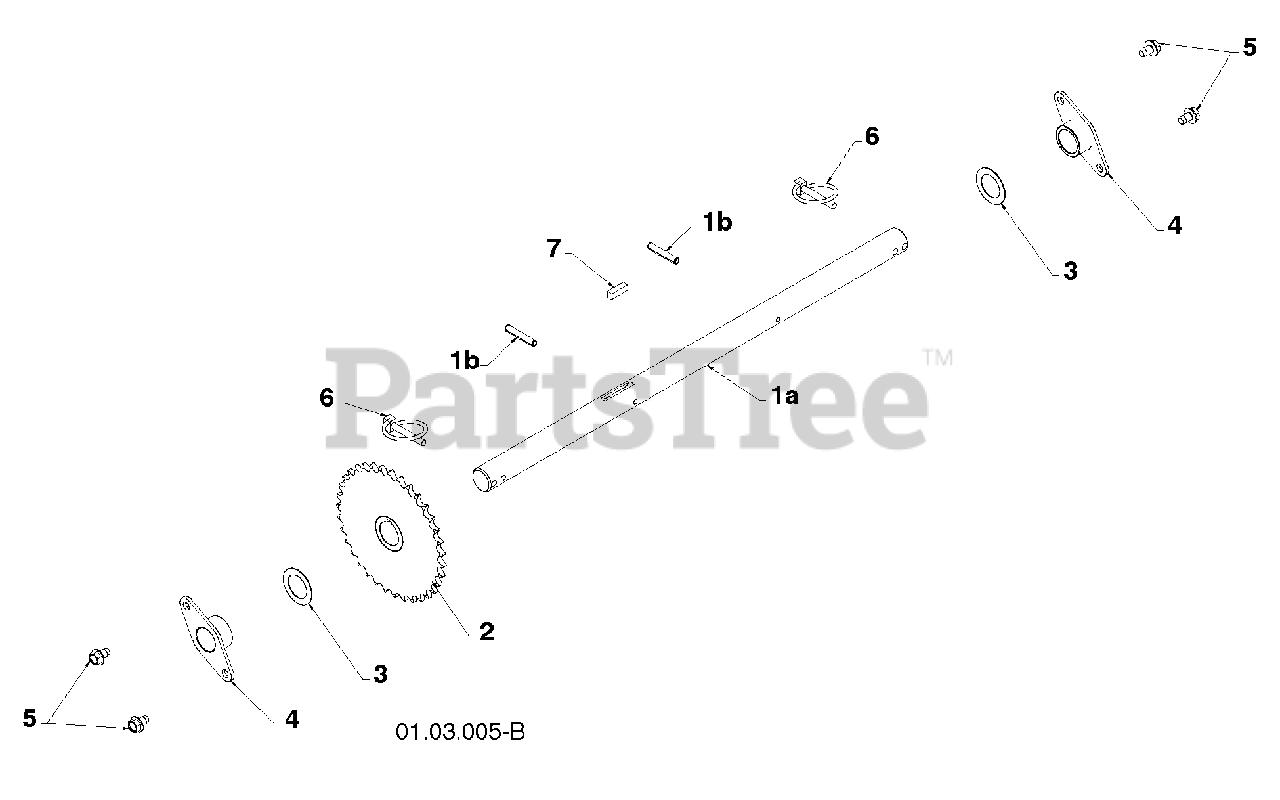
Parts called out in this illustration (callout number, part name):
1	(assy of 1a,1b) AXLE ASSEMBLY
2	SPROCKET
3	THRUST WASHER
4	BEARING
5	BOLT 5/16-18 X .500
6	CLIK PIN
7	SQUARE KEY
